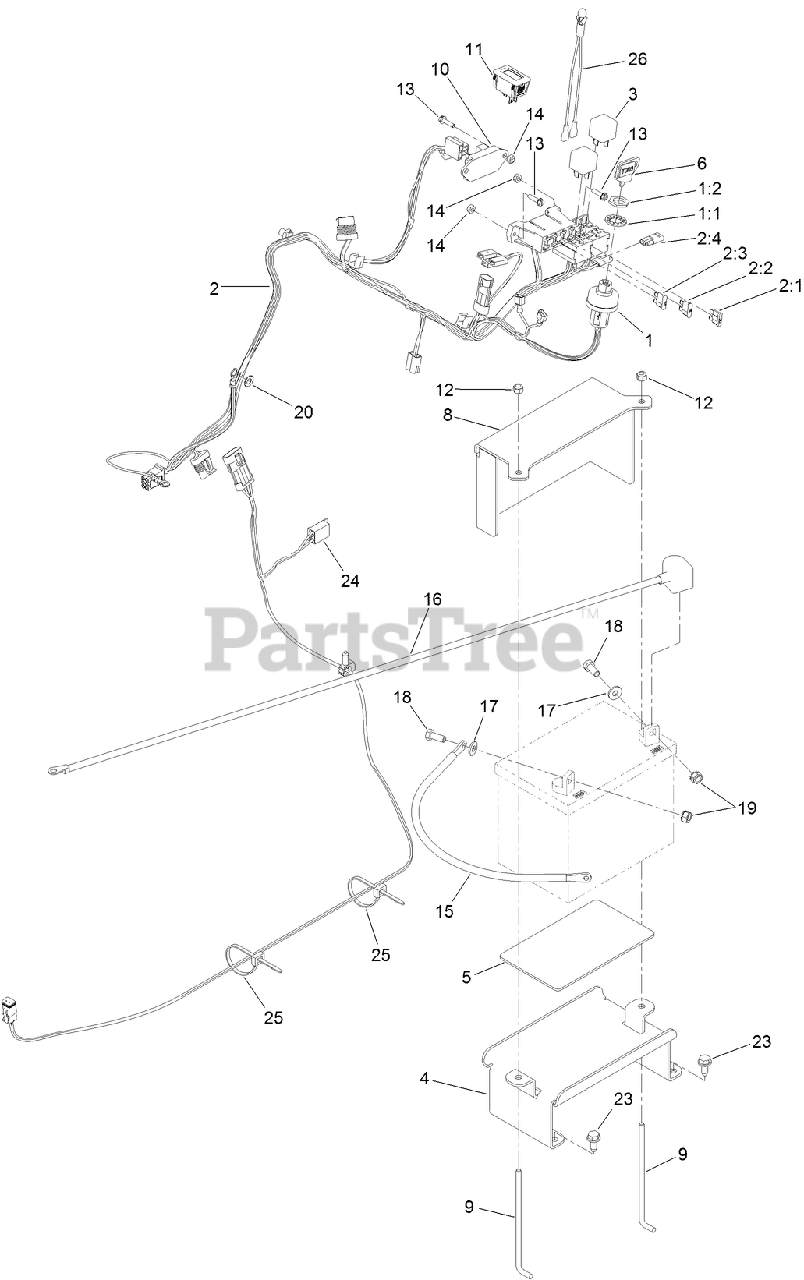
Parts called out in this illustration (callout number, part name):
1	IGNITION SWITCH ASM
1:1	WASHER-LOCK
2	HARNESS-WIRE
2:1	FUSE-BLADE, 30 AMP
2:2	FUSE-BLADE, 5 AMP
2:3	FUSE-BLADE, 20 AMP
2:4	CAP-PLUG
3	RELAY
4	TRAY-BATTERY
5	PAD-SKID, ANTI
6	KEY-IGNITION
8	COVER-BATTERY
9	HOLDOWN-BATTERY
10	MODULE-DELAY
11	HOURMETER
12	NUT-LOCK, NI
13	SCREW-HWH
14	NUT-LOCK, NI
15	CABLE-BATTERY, POSITIVE
16	CABLE-BATTERY, NEGATIVE
17	WASHER-FLAT
18	SCREW-HH
19	NUT-KEPS
20	WASHER-LOCK
23	SCREW-HWHTF
24	HARNESS-WIRE
25	TIE-CABLE
26	INDICATOR-LED, RED
